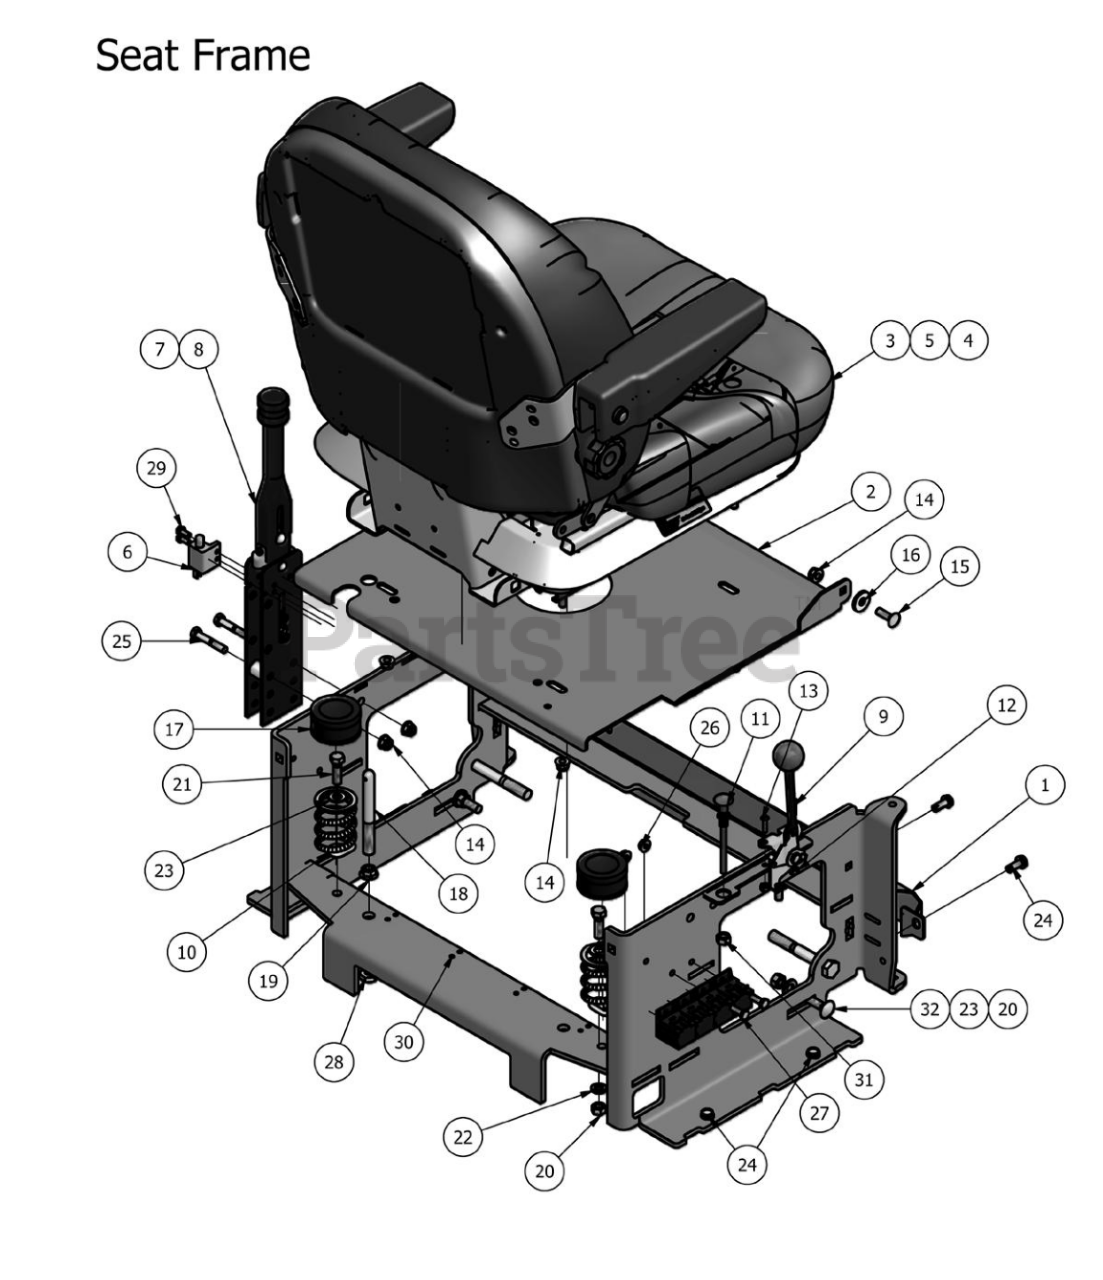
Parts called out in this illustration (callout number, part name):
1	Outlaw Cooler Cover
2	Aos, Diesel, Pup,Lightning Seat Plate
3	Suspension Seat
4	Seat Cable
5	Seat Switch Adaptor
6	Brake Handle Switch
7	Long Brake Cable
8	Hand Brake Assembly
9	Throttle Lever Assembly
10	Seat Spring
12	10-24 Nylon Insert Locknut Zinc Orange Nylon
13	10-24 x 3/4 Button Socket C/S 18-8 SS
14	5/16-18 Nylon Insert Flange Nut Zinc Orange Nylon
15	5/16-18 x 1 Carriage Bolts Zinc
16	.360ID Plastic Washer
17	Seat Bumper
19	1/2-13 Hex flange Nut Zinc w/Serrations
20	3/8 Nylock Flange Nut
21	3/8-16 x 1-1/4 GR 5 Hex Bolt Zinc
22	3/8 Lockwasher Zinc
23	3/8 USS Flat Washer Zinc
24	5/16 x 3/4 Hex Washer Head Type F Screw
25	5/16-18 x 1-3/4 Grade 5 Hex Bolt
26	1/4-20 Hex Flange Nuts Zinc W/Serrations
27	1/4-20 x 3/4 Grade 5 Hex bolts Zinc
28	1/2-20 Nylon Insert Jam Locknut Zinc Orange Zinc
29	12-24 x 1/2 Hex Washer Head bolt
30	12in Cable Tie Black
31	3/8-24 Hex Jam Nuts Zinc
32	3/8 x 1 1/2 Carriage Bolt
